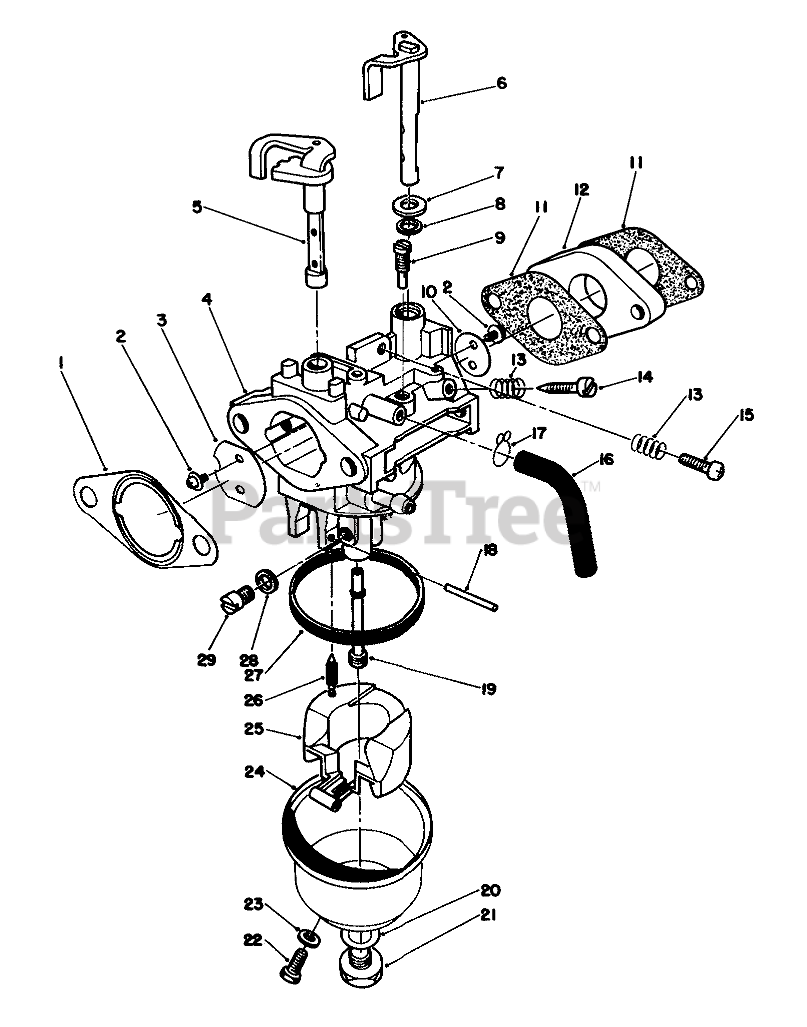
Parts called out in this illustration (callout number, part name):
1	GASKET F/W ENGINE
2	Screw
3	VALVE
4	BODY - CARB F
5	SHAFT
6	SHAFT
7	WASHER
8	Seal-Throttle Shaft
9	PILOT JET
10	VALVE
11	Gasket-Carburetor
12	CARB INSULATOR
13	SPRING-PILOT SCREW
14	ADJUSTER
15	SCREW
17	CLAMP
18	Pin
19	NOZZLE
20	GASKET
21	SCREW
22	SCREW
23	GASKET
25	Float
26	NEEDLE
27	FLOAT BOWL GASKET
28	SPACER
29	MAIN JET
